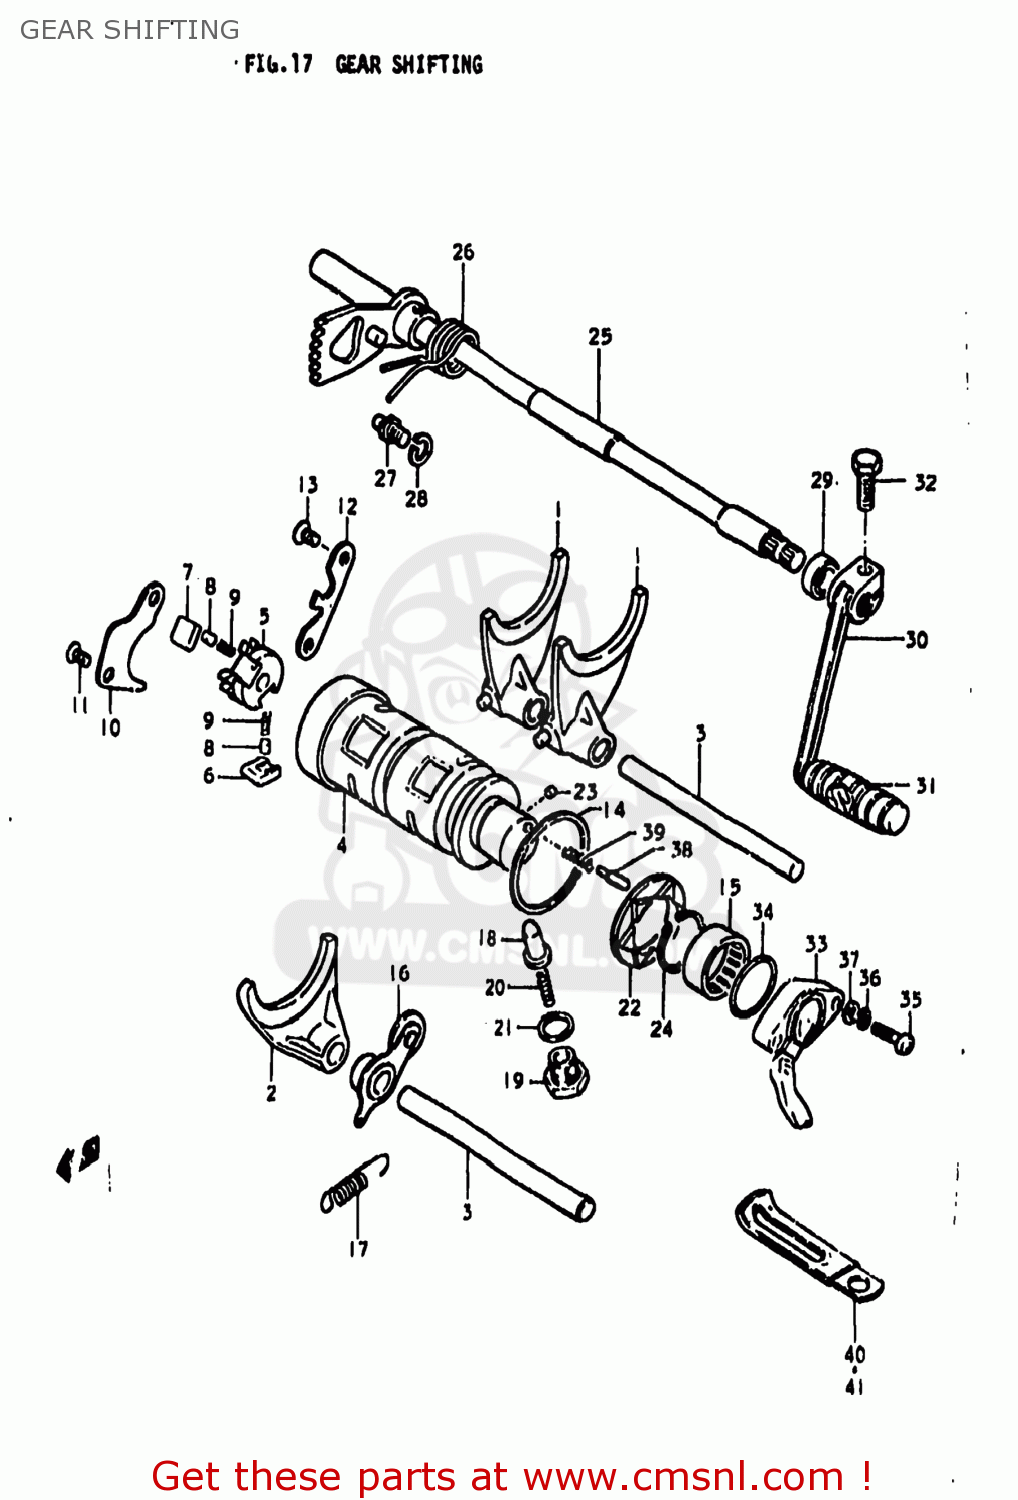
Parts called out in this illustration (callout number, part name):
1	FORK,GEAR SHIFT NO.1
2	FORK,GEAR SHIFT NO.3
3	SHAFT,GEAR SHIFT FORK
4	CAM,GEAR SHIFT
5	RETAINER,GEAR SHIFT CAM
6	PAWL,GEAR SHIFT NO.1
7	PAWL,GEAR SHIFT NO.2
8	PIN(5X8)
9	SPRING
10	LIFTER,GEAR SHIFT PAWL
11	SCREW
12	GUIDE,GEAR SHIFT CAM
13	SCREW
14	WASHER(40X45X1)
15	BEARING(25X32X12)
16	STOPPER,GEAR SHIFTING
17	SPRING
18	STOPPER,GEAR SHIFT CAM NO.2
19	HOLDER,GEAR SHIFT CAM STOP SPR
20	SPRING
21	GASKET(14X19.2X2) (NAS)
22	PLATE,GEAR SHIFT CAM STOPPER
23	PIN 4X6
24	CIRCLIP
25	SHAFT,GEAR SHIFT
26	SPRING
27	STOPPER,GEAR SHIFT CAM
28	WASHER
29	OIL SEAL
30	LEVER ASSEMBLY,GEAR SHIFTING
31	RUBBER,GEAR SHIFT PEDAL
32	BOLT
33	BASE ASSEMBLY,NEUTRAL SWITCH TERMINAL
34	O-RING (D:2.4 ID:26.2)
35	SCREW 5X20
36	LOCK WASHER
37	WASHER
38	PIN(5X15.5)
39	SPRING
40	CLAMP L:35
41	CLAMP
